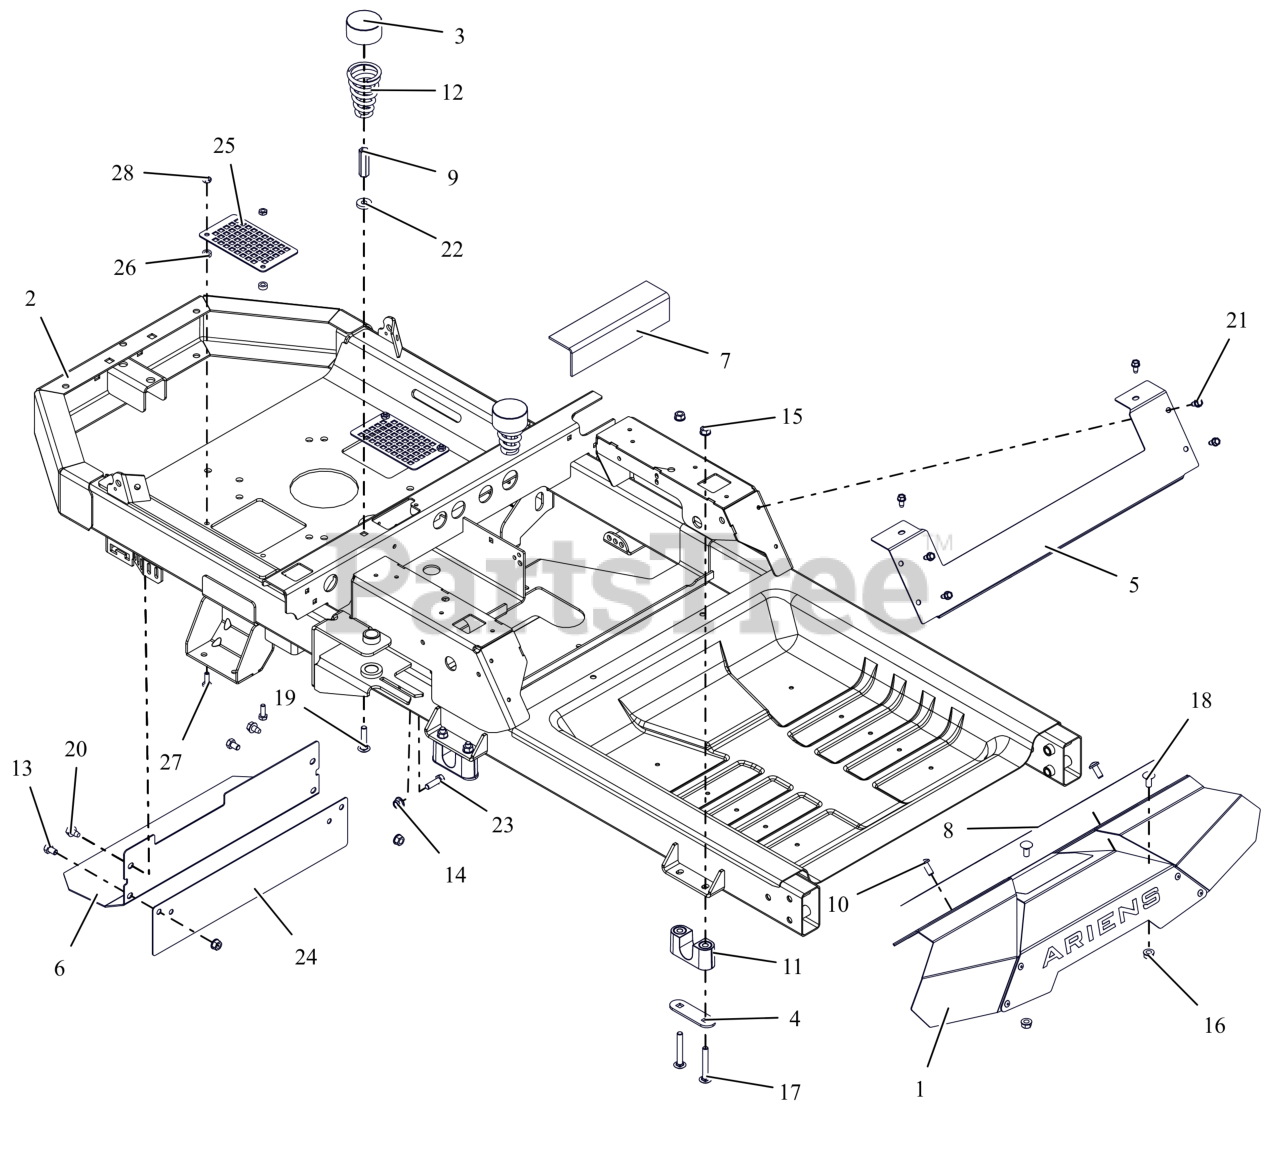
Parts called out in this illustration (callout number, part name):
1	KIT, IKON FOOT REST W/DECAL
2	WLDMT, FRAME IKON XD/ZTX & XL (ORANGE)
3	HUB CAP
4	PLATE, BEARING SUPPORT
5	PLATE, SEAT KICK
6	HEAT, SHIELD
7	PAD, RUBBER-TANK
8	GRIP TAPE, FOOT PLATE
9	NUT, COUPLING .31-18X1.75 ZCC
10	SCR-RDHDSKTAP .31-18X.75 ZCC
11	BSHG, DECK LIFT PIVOT
12	SPRING, SEAT
13	BLT, HEX .31-18X.50 GR5 ZCC
14	NUT,LK-NYL-FLG .31-18 G5ZC120
15	NUT,LK-CTR-FLG .31-18 GF ZCC
16	NUT-LK-TOP-FLG .312-18 GF ZCC
17	BLT, RHSSN.31-18X2.25 G5 ZCC
18	BLT,RHSN .31-18X.75 G5 ZCC
19	BLT,RHSN .31-18X1.50 G5 ZCC
20	SCR,TAP .312-18X.50 HWH TR ZCC
21	SCR-TAP .25-20X.50 HWH ZCC
22	WSHR, FLT .328X.870X.179 ZCC
23	BLT,HEX .31-18X1.00 G5 ZCC
24	GUARD, REAR CLUTCH
25	GUARD, VENT
26	BSHG-SLV .265X.500X.219
27	BLT, HEX .25-20X.75 G5 ZCC
28	NUT-LK-CTR-JAM .250-20 GB ZCC
